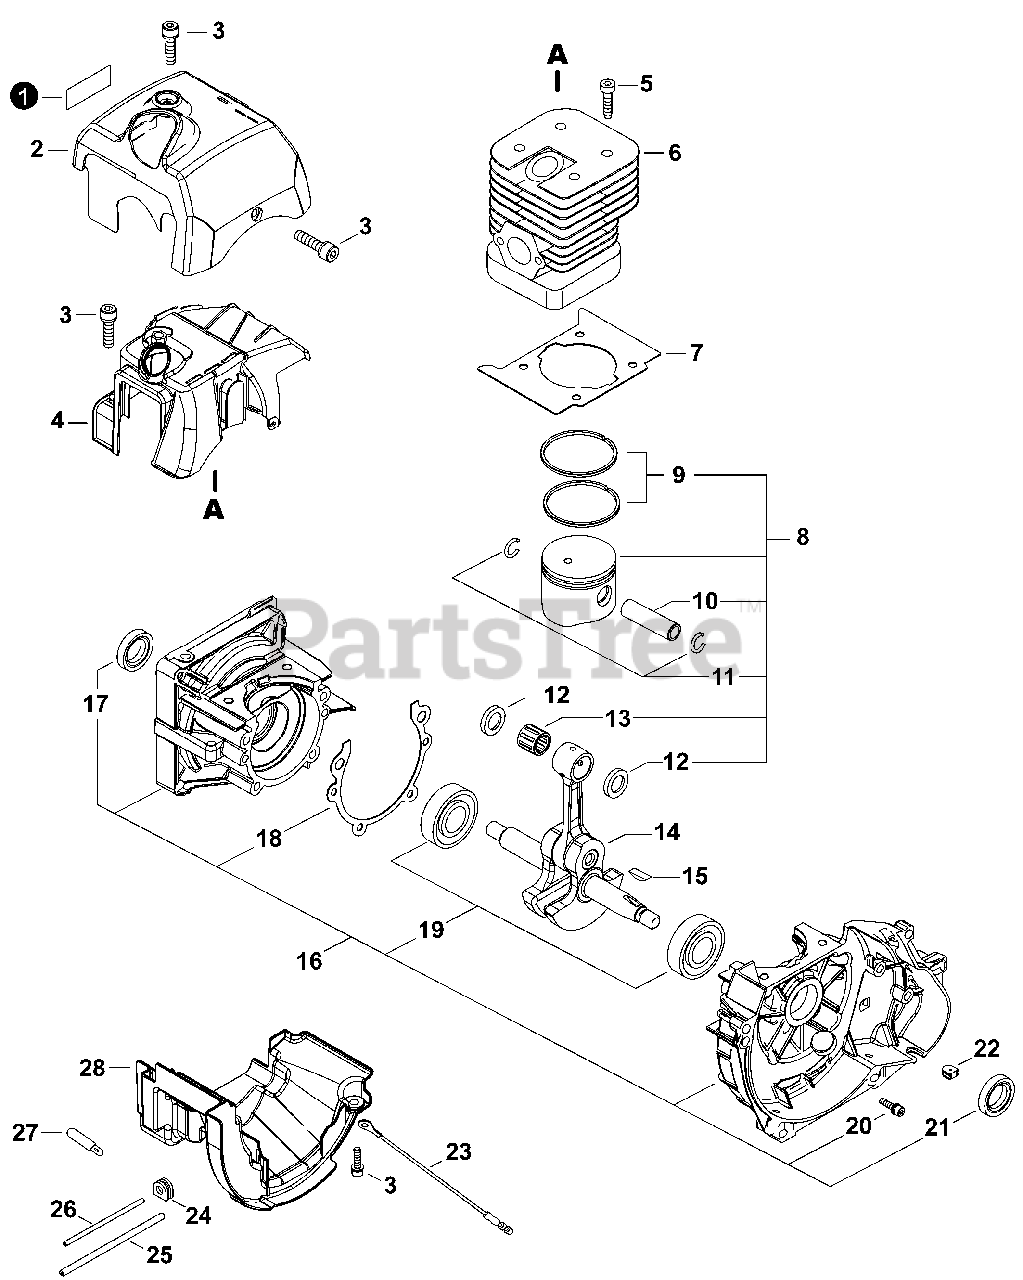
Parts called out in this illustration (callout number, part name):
1	LABEL - MODEL SRM-420ES
2	COVER, ENGINE
3	BOLT, TORX 5x16
4	COVER, CYLINDER
5	BOLT, TORX 5x20
6	CYLINDER
7	GASKET, CYLINDER
8	PISTON KIT
9	RING, PISTON
10	PIN, PISTON 10
11	RING, SNAP 10
12	WASHER, THRUST
13	BEARING, NEEDLE
14	CRANKSHAFT ASSY
15	KEY, WOODRUFF
16	CRANKCASE SET
17	SEAL, OIL 12
18	GASKET, CRANKCASE
19	BEARING, BALL 6201
20	BOLT, TORX 5x35
21	SEAL, OIL 12
25	TUBE, INSULATOR 8x9x111
26	PIPE, FUEL 3x6x165 BLACK
28	PLATE, INSULATOR
